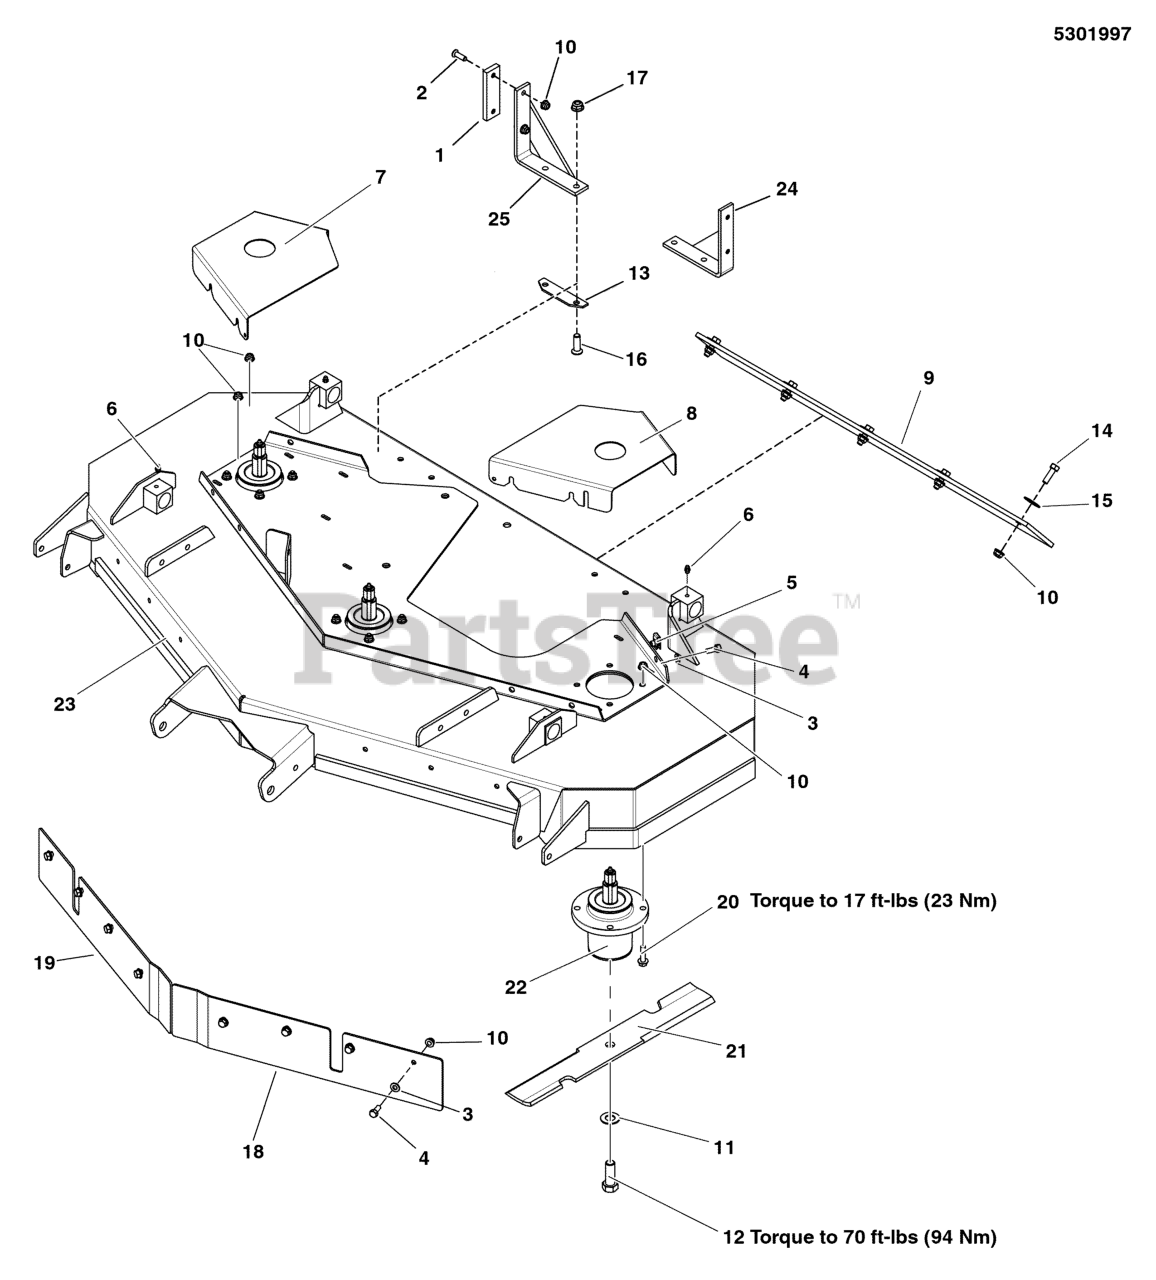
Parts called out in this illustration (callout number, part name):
1	PAD, FRICTION, .375 X 1.25 X 4.00
2	SCREW, 5/16-18 X 1, PHILLIPS HD, BZ
3	WASHER, 5/16" SAE
4	BOLT, 5/16-18 X 3/4 GD5
5	BODY CLIP, 5/16-18-7GA MATERIAL
6	GREASE FITTING, 1/4-28 STRAIGHT
7	GUARD, DECK, 52, RH, SW30 - RED
8	GUARD, DECK, 52, LH, SW30 - RED
9	FLAP, CCW RD
10	NUT, 5/16-18 HEX NYLOCK FLANGE
11	WASHER, 5/8 GRADE 8, YZ
12	BOLT, 5/8-11 X 1-3/4 GD8
13	PLATE, BRACKET SUPPORT - RED
14	BOLT, 5/16-18 X 1 GD5 YZ
15	WASHER, 5/16 FENDER
16	BOLT, Carriage, 3/8-16 X 1
17	NUT, 3/8-16 HEX NYLOCK FLANGE
18	BAFFLE,FRONT DISCHARGE,LH,52RD SW30, RED
19	BAFFLE,FRONT DISCHARGE,RH,52RD SW30, RED
20	BOLT, 5/16-18 X 1 1/4 FLANGE
21	BLADE, 18 (SET OF THREE)
22	ASSM, SPINDLE, LOW PROFILE
23	DECK SHELL W/ DECALS, 52", SW30RDCE
24	WELD, FRICTION PAD HOLDER, LH - RED
25	WELD, FRICTION PAD HOLDER, RH - RED
